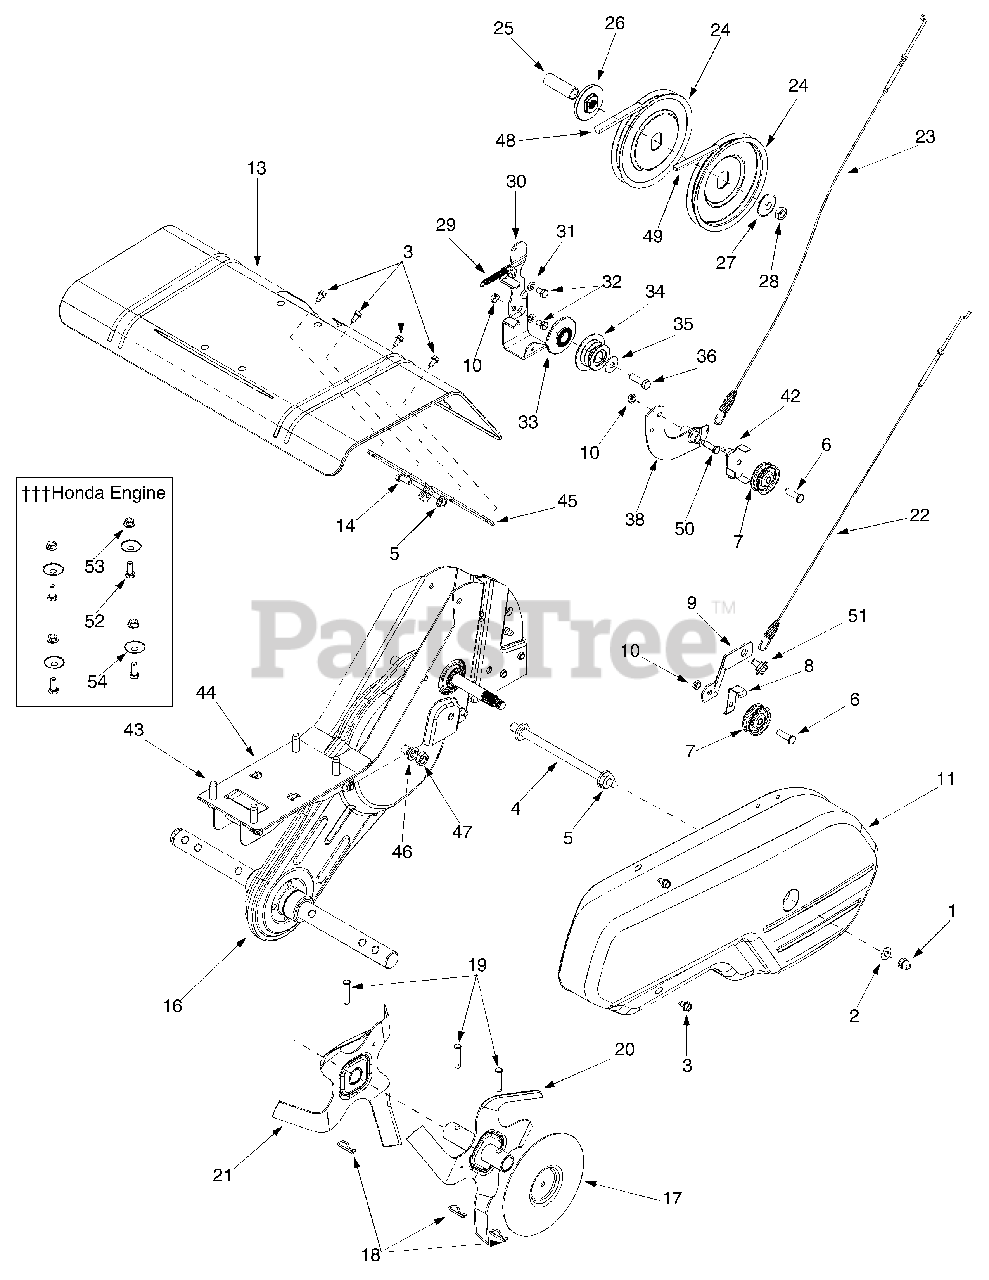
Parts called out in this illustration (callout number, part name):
1	Hex L-Stop nut 1/4-28
2	Flat Wash.266" I.D. x.625" O.D.
3	Hex Washer TT-Tap Scr. 1/4-20 x.5"
4	Belt Cover Bolt
5	Hex Flange Top L-Nut 5/16-18
6	Hex Hd. Scr. 3/8-16 x 1.25" Lg.
7	Flat Idler Pulley 2.12" O.D.
8	Idler Belt Keeper
9	Idler Bracket
10	Hex Cent. Jam Nut 3/8-16 Thd.
14	Hex Hd. Cap Scr. 5/16-18 x.75" Lg
16	Chain Case Assembly Complete
17	Outer Disc Plate Assembly
18	Internal Cotter Pin
19	Clevis Pin
20	Outer Tine Assembly L.H.
20	Outer Tine Assembly R.H.
21	Inner Tine Assembly L.H.
21	Inner Tine Assembly R.H.
22	Forward Clutch Cable
23	Reverse Clutch Cable
24	Fl-Pulley 6" Dia.
25	Spacer.64" Dia. x 2.4" Lg.
26	Pulley Mounting Adapter
27	Bell-Wash.525" I.D. x 1.5" O.D.
28	Hex Jam Nut 1/2-20 Thd.
29	Return Spring
30	Reverse Bracket
31	Lock Washer 5/16
32	Hex Bolt 5/16-24 x.625"
33	Engine Inner Half Pulley
34	Reverse Engine Pulley
35	Bell Washer.396" I.D. x 1/14" O.D.
36	Hex Bolt 3/8-24 x 1.00"
38	Reverse Arm Assembly
42	Reverse Belt Keeper
43	Hex L-Wash. TT-Tap 3/8-16 x 1.25"
45	Tine Shield Bracket
46	L-Wash. 7/16" I.D.
47	Hex Nut 7/16-20 Thd.
48	V-Belt (Forward) 1/2 x 41.9"
49	V-Belt (Reverse) 3/8 x 45.68"
50	Shld. Screw.498 x 1.445
51	Shld. Screw.560 x.165
52	Screw 5/16-18 x 1.50
53	Hex Nut 5/16-18
54	Bell Washer
